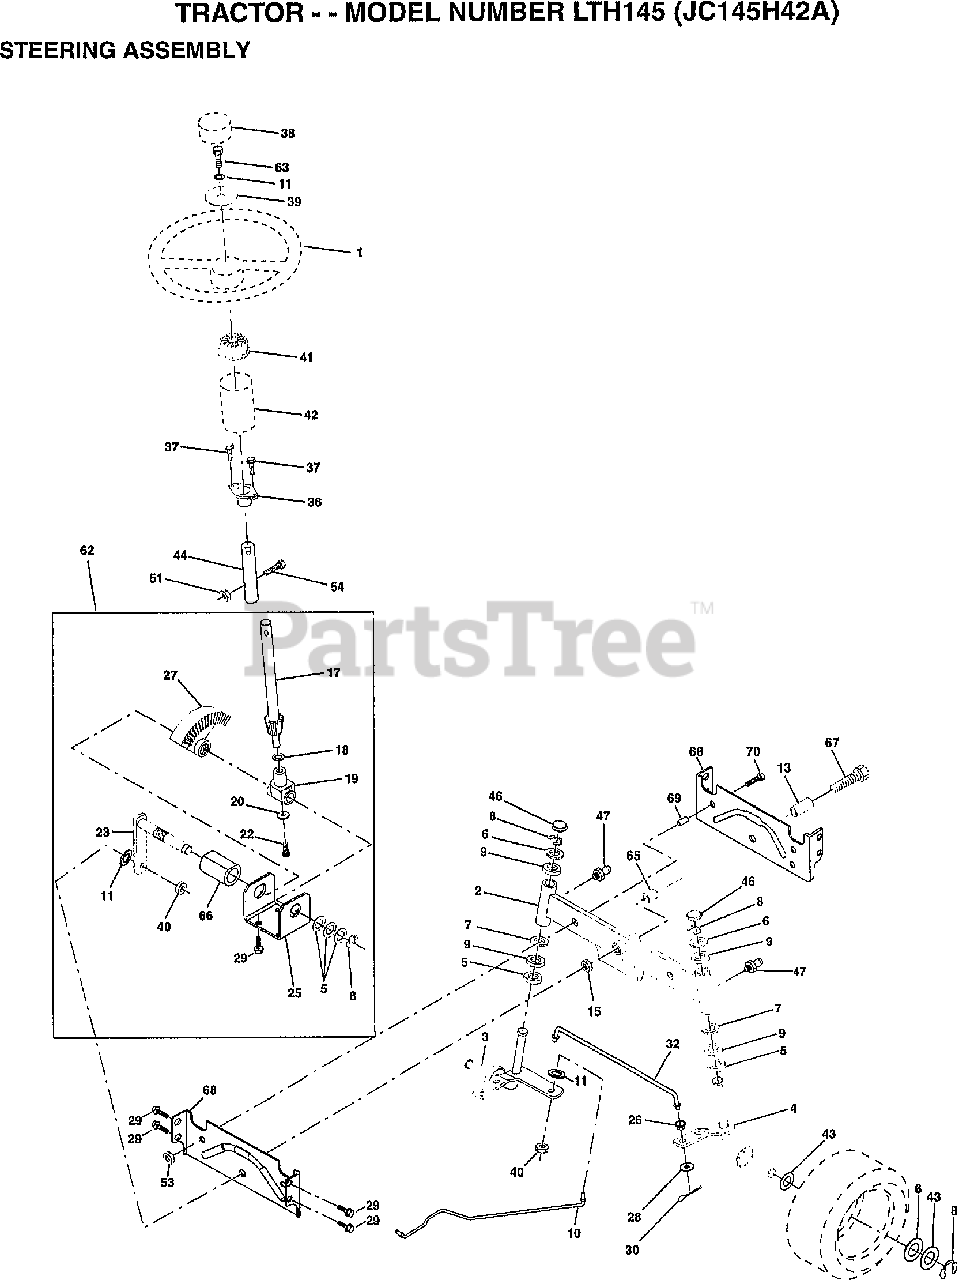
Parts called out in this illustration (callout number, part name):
7	WASHER 27/32 X 1-1/4 X 16 GA
8	RING KLIP #T5304-75
11	WASHER LOCK HVY HLCL SPR 3/8
15	NUT LOCK FLANGE 5/8-11
20	WASHER T
22	SCREW HEX SOCKET 1/4-20 X 5/8
28	WASHER
29	SCREW THDROL 3/8-16X3/4 TY-TT
30	PIN COTTER 1/8 X 3/4 CAD
39	WASHER 13/32 X 2-3/8 X 8 GA
51	LOCKNUT
53	NUT, CROWNLOCK 3/8-16
54	BOLT FIN HEX 5/16-18 UNC X 1-1/4
63	BOLT FIN HEX 3/8-16 X 1
67	BOLT FIN HEX 5/8-11 X 2-3/4
70	BOLT FIN HEX 3/8-16 X 2-1/4
